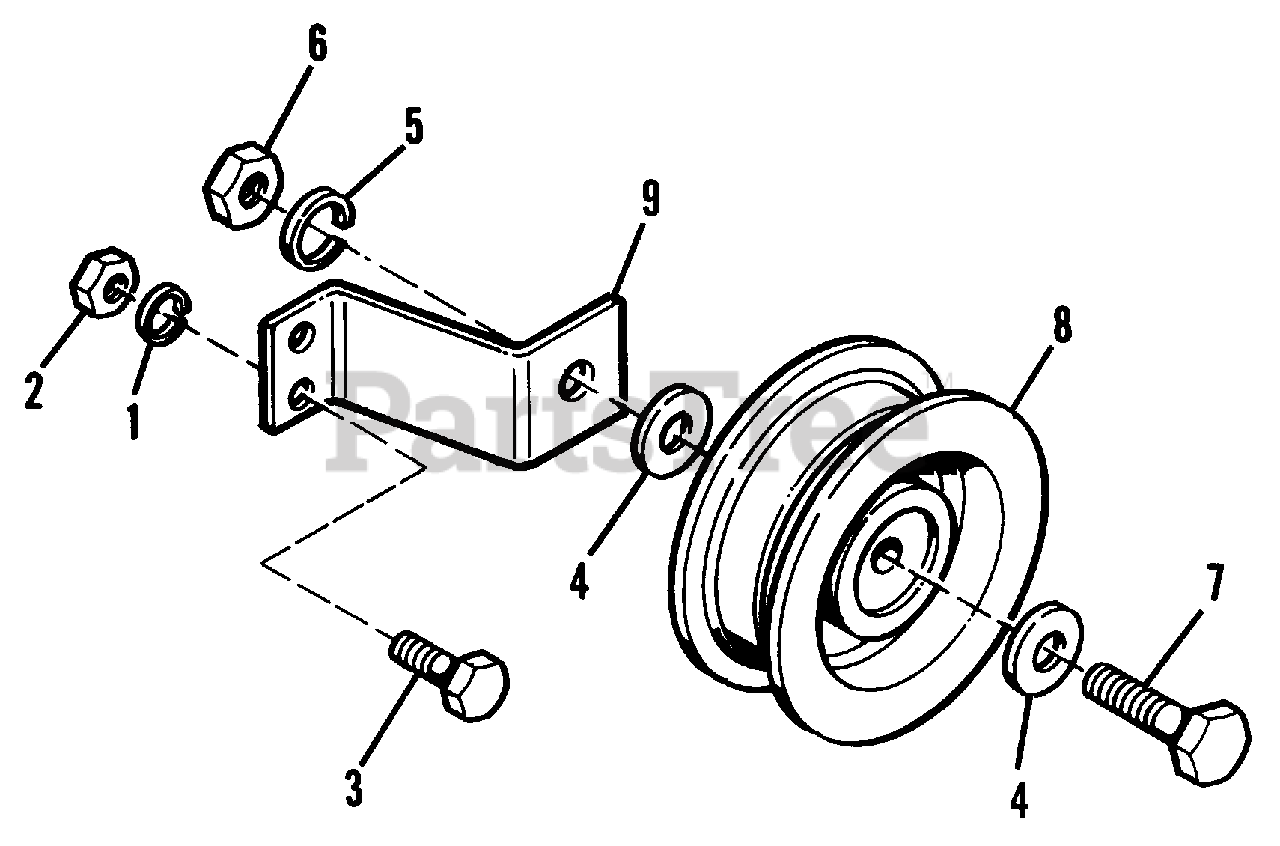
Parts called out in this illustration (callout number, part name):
1	LOCKWASHER, 5/16
2	NUT, Hex, 5/16-18
3	CAPSCREW, 5/16-18 x 3/4, Gr. 5
4	WASHER, Plain
5	LOCKWASHER, 3/8
6	NUT, Hex, 3/8-16
7	CAPSCREW, Hex Hd., 3/8-16 x 1-1/4, Gr. 5
8	PULLEY, Idler
9	BRACKET, Idler
